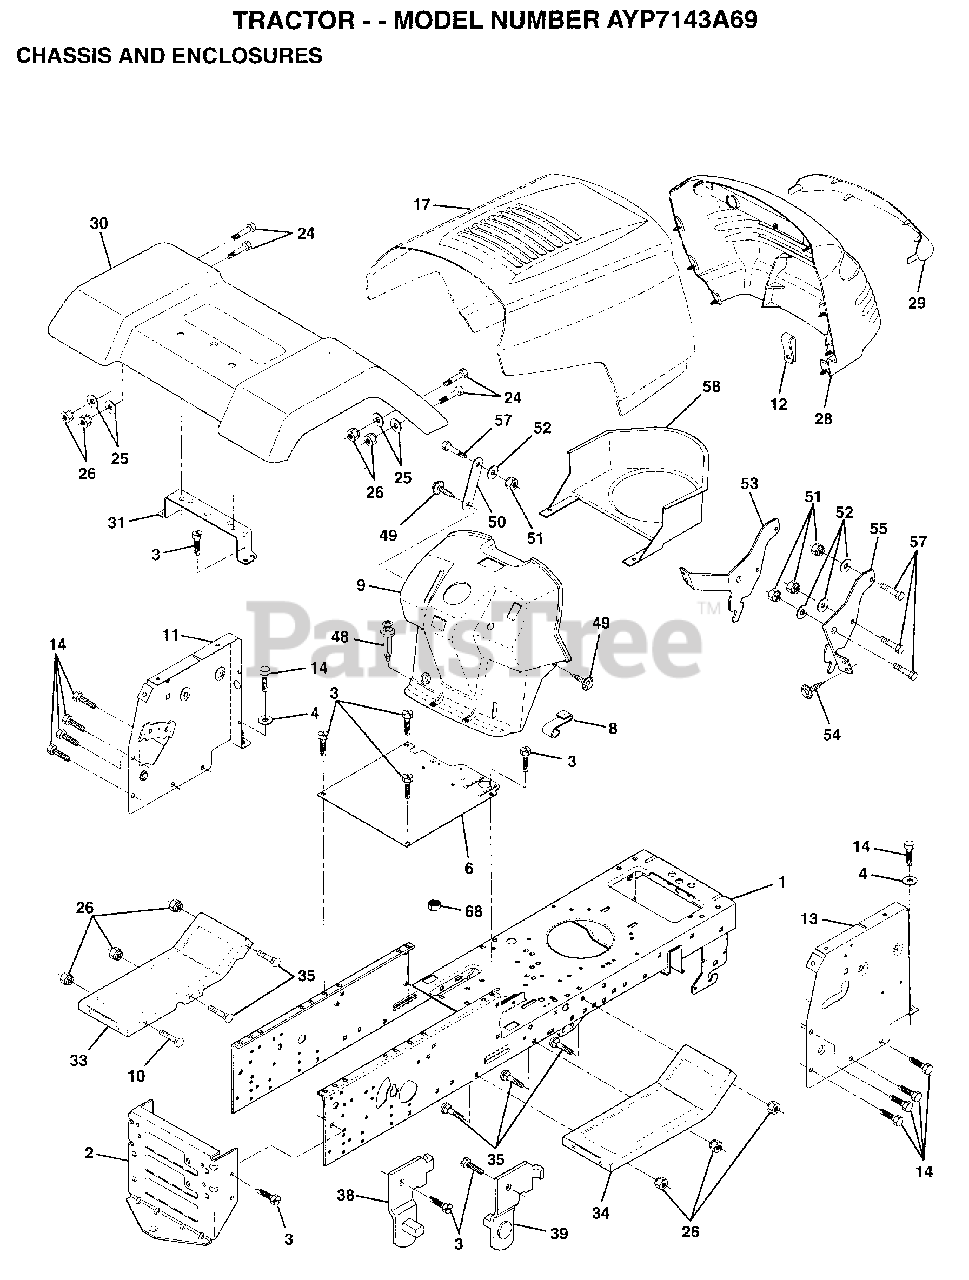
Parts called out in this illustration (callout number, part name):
1	CHASSIS.WLD.11GA
3	SCREW
4	WASHER
8	"CLIP,INSULATOR"
11	PANEL.DASH.LH.
12	CLIP.TINNERMAN
13	PANEL.DASH.RH
14	SCREW LT
24	BOLT
25	WASHER
26	NUT
29	LENS GRILLE
30	FENDER
31	BRKT FENDER
33	FOOTREST LH
34	FOOTREST RH
35	BOLT
38	BRACKET ASM LH
39	BRACKET ASM RH
48	RIVET.PUSH.PLATE
49	SCREW HEX CRT
50	BRACE SUPT DASH
51	NUT
52	WASHER
53	BRACKET.GRILLE.LH
55	BRACKET.GRILLE.RH
58	DUCT AIR 12-15H
68	NUT
